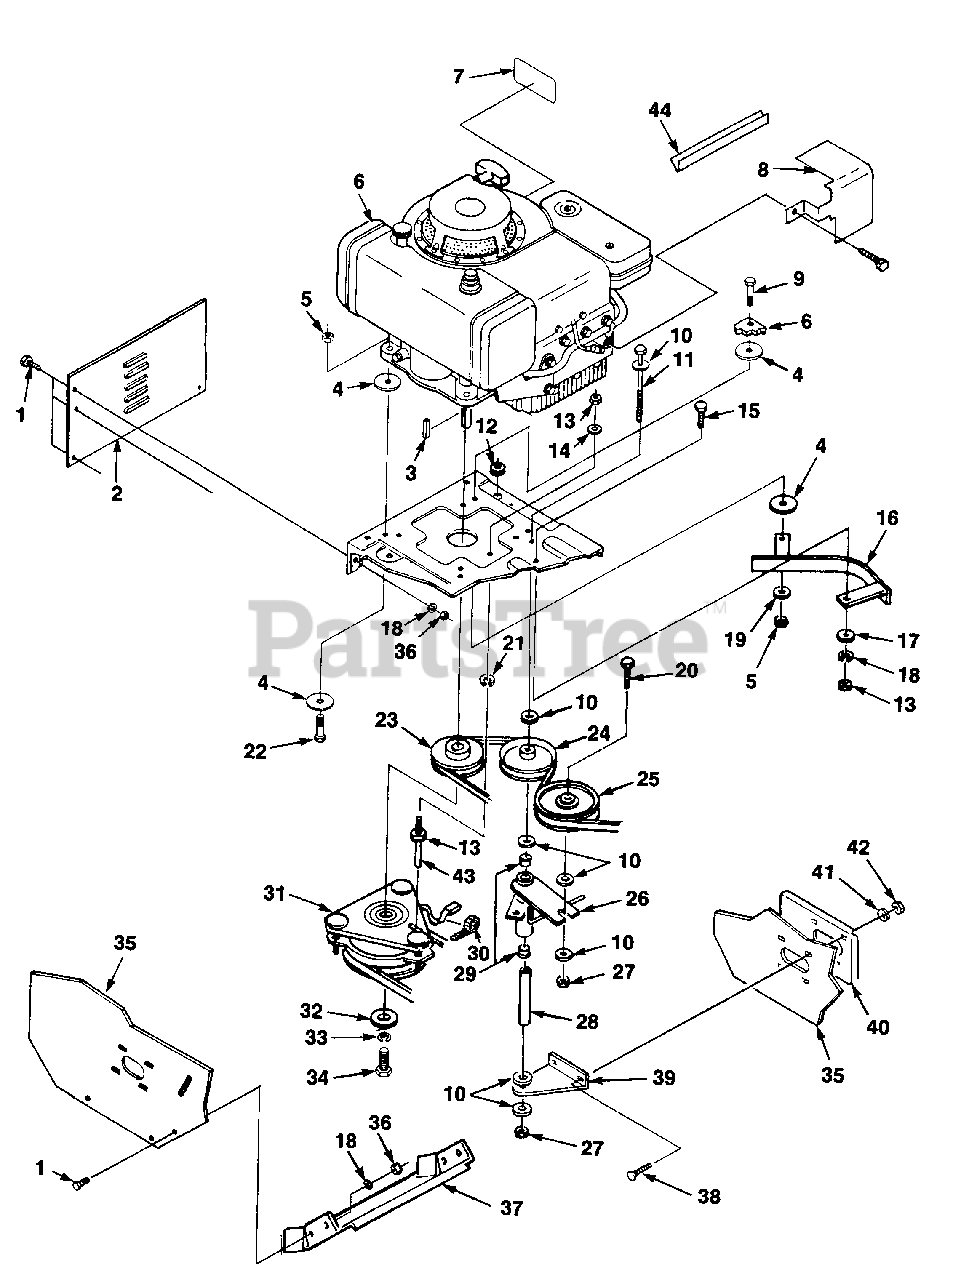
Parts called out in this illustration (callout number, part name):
2	PANEL- Rear
9	SCREW- (5/16-18 x 1 3/4")
10	WASHER- Flat (3/8")
13	Superseded by 81018
14	Superseded by UP07173
15	Superseded by 80052
17	Superseded by 84026
20	Superseded by UP07178
21	Superseded by UP03407
22	SCREW- (5/16-18 x 1 1/2")
23	PULLEY- Engine
24	PULLEY- Idler
27	Nut (Hex Locking)
36	Superseded by JA993730
37	PAN-Bottom
40	SUPPORT- Frame
41	Superseded by UP03409
42	Nut - hex 1/4-20 lock
